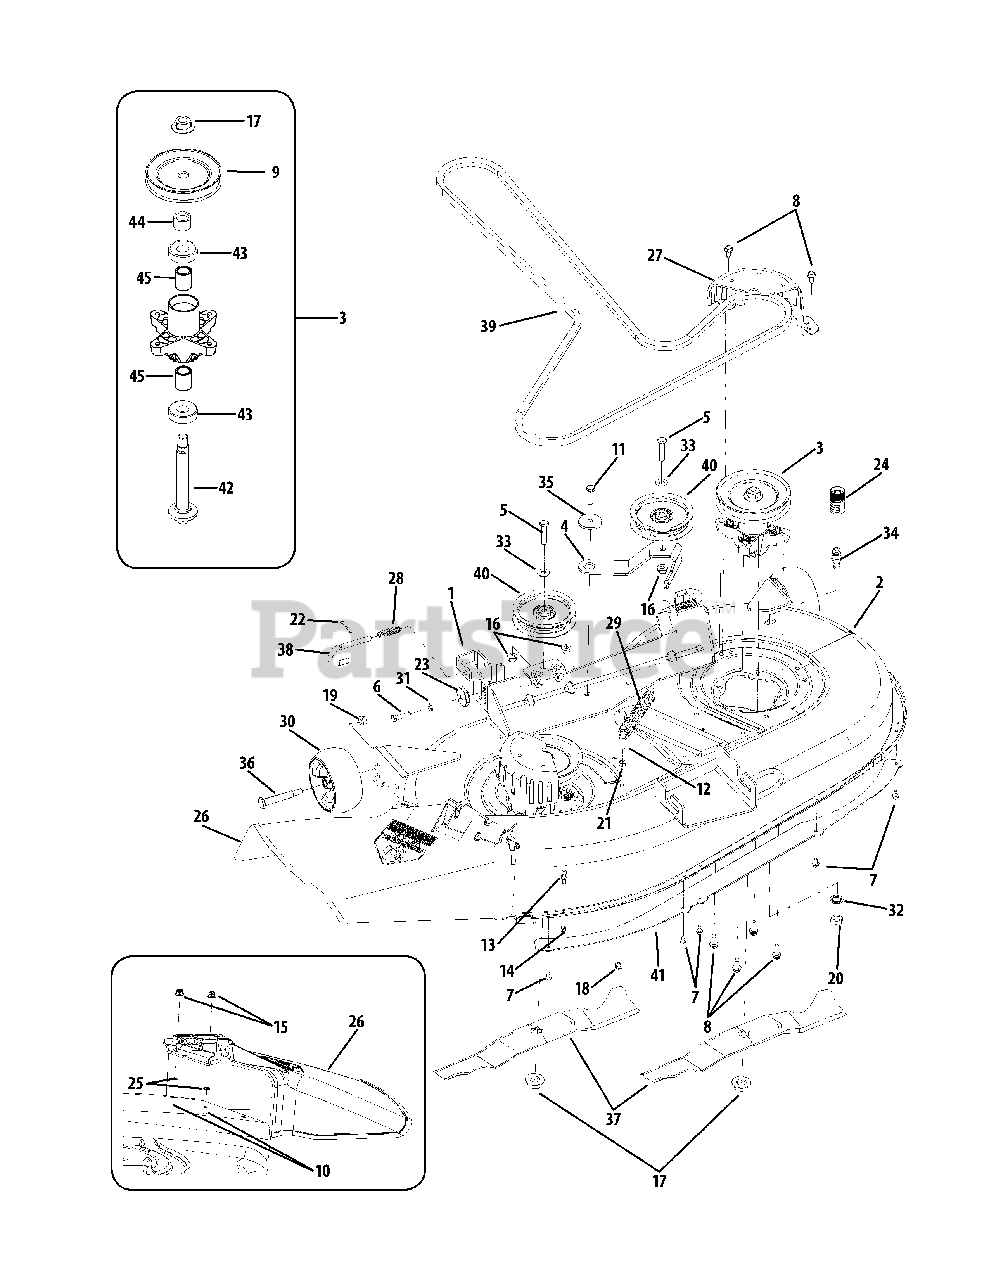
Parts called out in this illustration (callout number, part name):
1	Deck Lift Bracket
2	Deck Housing
3	Spindle Assembly
4	Idler Arm
5	Hex Cap Screw, 3/8-16 x 1.75
6	Hex Cap Screw, 5/16-18 x 1.25
7	Hex Washer Head Screw, 1/4-20 x .5
8	Hex Washer Head Screw, 5/16-18 x .750
9	Deck Pulley, 6.3 Dia
10	Hex Cap Screw, 1/4-20 x .62
11	Hex Cap Screw, 3/8-16 x 1.25
12	Hex Cap Screw, 5/16-18 x 1.75
13	Grass Catcher Pin, 1/4-20
14	Hex Insert Lock Nut, 1/4-20
15	Hex Insert Flange Lock Nut, 1/4-20
16	Hex Insert Flange Lock Nut, 3/8-16
17	Hex Flange Nut, 5/8-18
18	Hex Insert Lock, 5/16-18
19	Hex Flange Lock Nut, 3/8-16
20	Hex Nut, M16-1.5
21	Hex Nut, 5/16-18
22	Cotter Pin, 1/8 x 1.25
23	Deck Adjustment Gear
24	Water Nozzle Adapter
25	Push Nut, .25 x .5
26	Discharge Chute Assembly
27	Belt Cover
28	Compression Spring
29	Extension Spring, .94 Dia. x 6.74
30	Deck Ball Wheel, 5.0
31	Lock Washer, 5/16
32	Lock Washer
33	Flat Washer, .38 x .93 x .11
34	Deck Water Nozzle
35	Shoulder Spacer, .884 x .19
36	Shoulder Screw, .5 x 2.5 x 3/8-16
37	Blade, 3 in 1, 21.23
38	Deck Hanger Rod
39	V-Belt
40	Idler Pulley, 4.25 Dia
41	Deck Skirt
42	Spindle Shaft, 5.75
43	Ball Bearing
44	Spacer, .820 x 1.15 x .73
45	Spacer, .8 x 1.10 x 1.322
